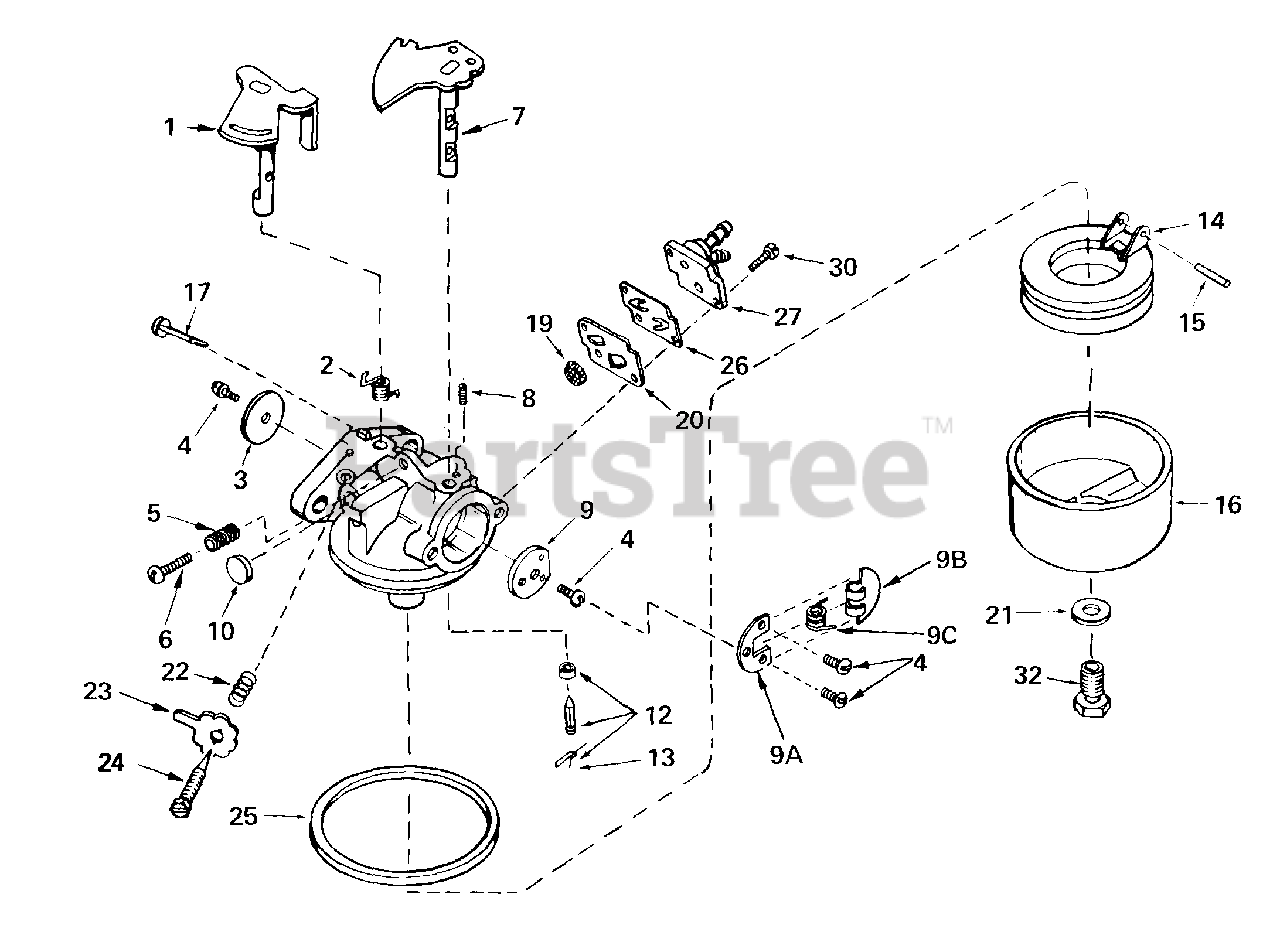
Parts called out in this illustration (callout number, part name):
1	"Shaft & Lever Assy., Throttle
2	Spring, Throttle return
3	Shutter, Throttle
4	Screw, Throttle & Choke shutter
5	Spring, Regulating screw
6	Screw, Regulating
7	Shaft & Lever Assy., Choke
8	Spring, Choke positioning
9A	Shutter, Choke
9B	Shutter, Choke
9C	Spring, Shutter
10	Plug, Welch
12	Inlet Needle, Seat & Clip Assy.
13	Clip, Inlet needle
14	Float, Carburetor
15	Shaft, Float
16	Bowl, Float
17	Element, Pump
19	Screen, Filter
20	Gasket
21	Gasket, Bowl-to-body
22	Spring, Idle adj. screw
23	Knob, Idle adj. screw
24	Screw, Idle adj.
25	Gasket, Bowl-to-body
26	Valve, Flap
27	Cover Assy., Valve
32	Nut, Float bowl
